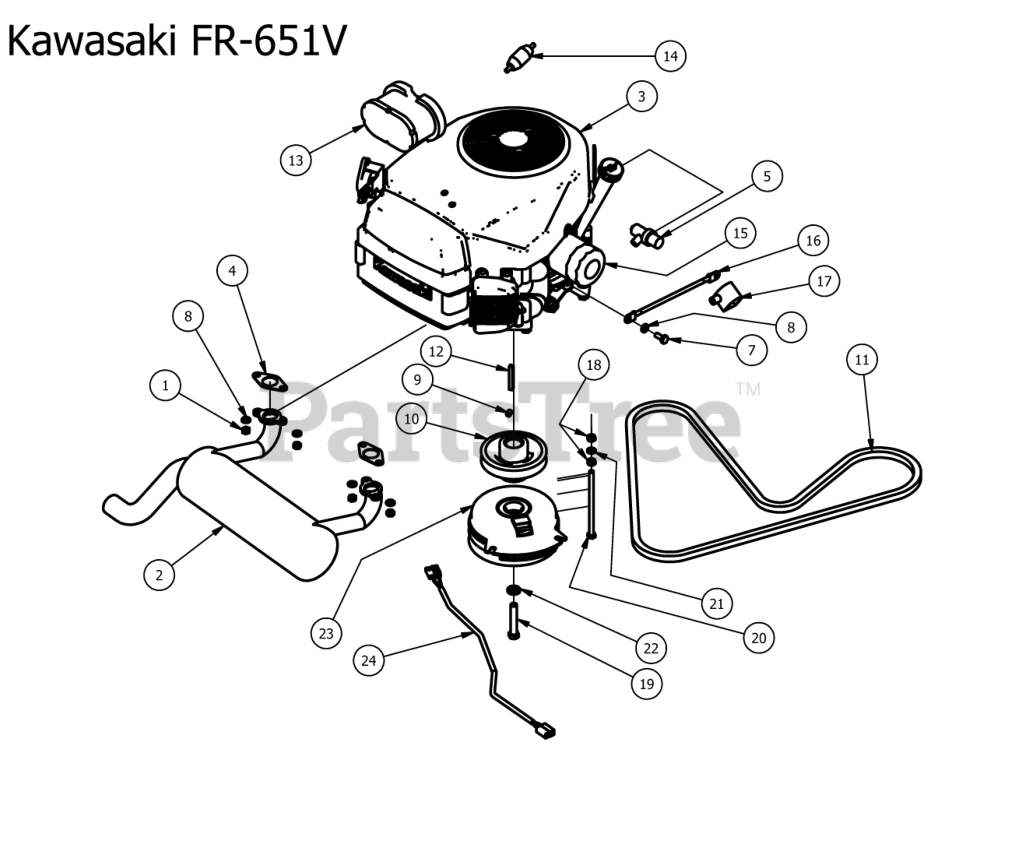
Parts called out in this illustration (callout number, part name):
1	M8-1.25 Zinc Nut
2	Exhaust-Stand On (kawasaki engine)
3	kawasaki FR-651V
4	Exhaust gasket
6	3/8 x 1 1/8 bolt
7	M8x1.20x20MM Hex head bolt
8	5/16" Lock Washer
9	5/16 Set Screw
10	4 3/4 Motor Pulley
12	1/4 x 2 Square key Stock
13	Kaw air Filter For Engine
14	Universal inline Fuel Filter
15	Oil Filter
16	Ground Cable
17	Black Boot For ground cable
19	7/16" x 2 1/2" Hex Bolt
20	5/16-18 x 5-1/2 GR 5 Hex Bolt
21	5/16" Lock Washer
22	7/16" Lock Washer
23	Clutch Assembly
24	Clutch Pigtail
